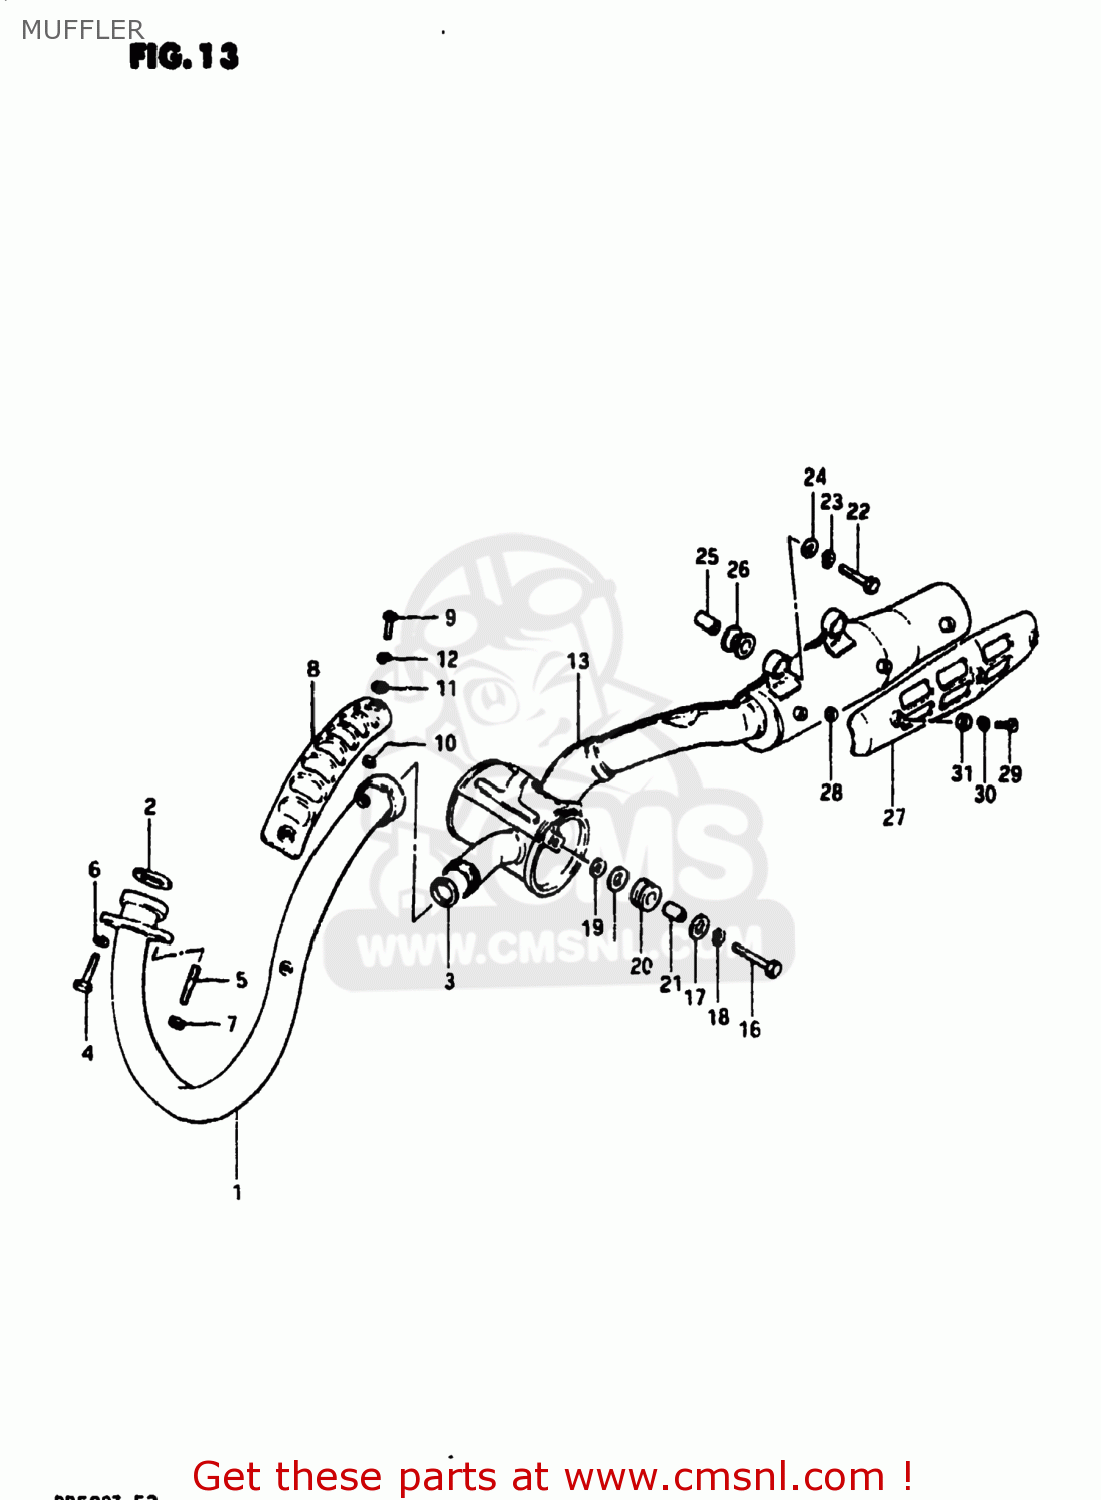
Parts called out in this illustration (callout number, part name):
1	PIPE,EXHAUST
2	GASKET,EXHAUST PIPE (NAS)
3	GASKET,EXHAUST PIPE (NAS)
4	BOLT
5	STUD 8X20
6	LOCK WASHER
7	NUT
8	COVER,EXHAUST PIPE
9	SCREW 6X12
10	GASKET 6.2X12X1.5 (MCA)
11	WASHER
12	LOCK WASHER
13	MUFFLER ASSEMBLY
14	PLUG(12X9)
15	GASKET(12X16X2) (NAS)
16	BOLT
17	WASHER (8.5X29X1.6)
18	LOCK WASHER
19	GASKET
20	CUSHION
21	SPACER (8.6X13.8X13)
22	BOLT 8X40
23	LOCK WASHER
24	WASHER (8.5X29X1.6)
25	SPACER (8.6X12X17.5)
26	CUSHION
27	COVER,SECOND MUFFLER
28	GASKET 6.2X12X1.5 (MCA)
29	SCREW 6X12
30	LOCK WASHER
31	WASHER
